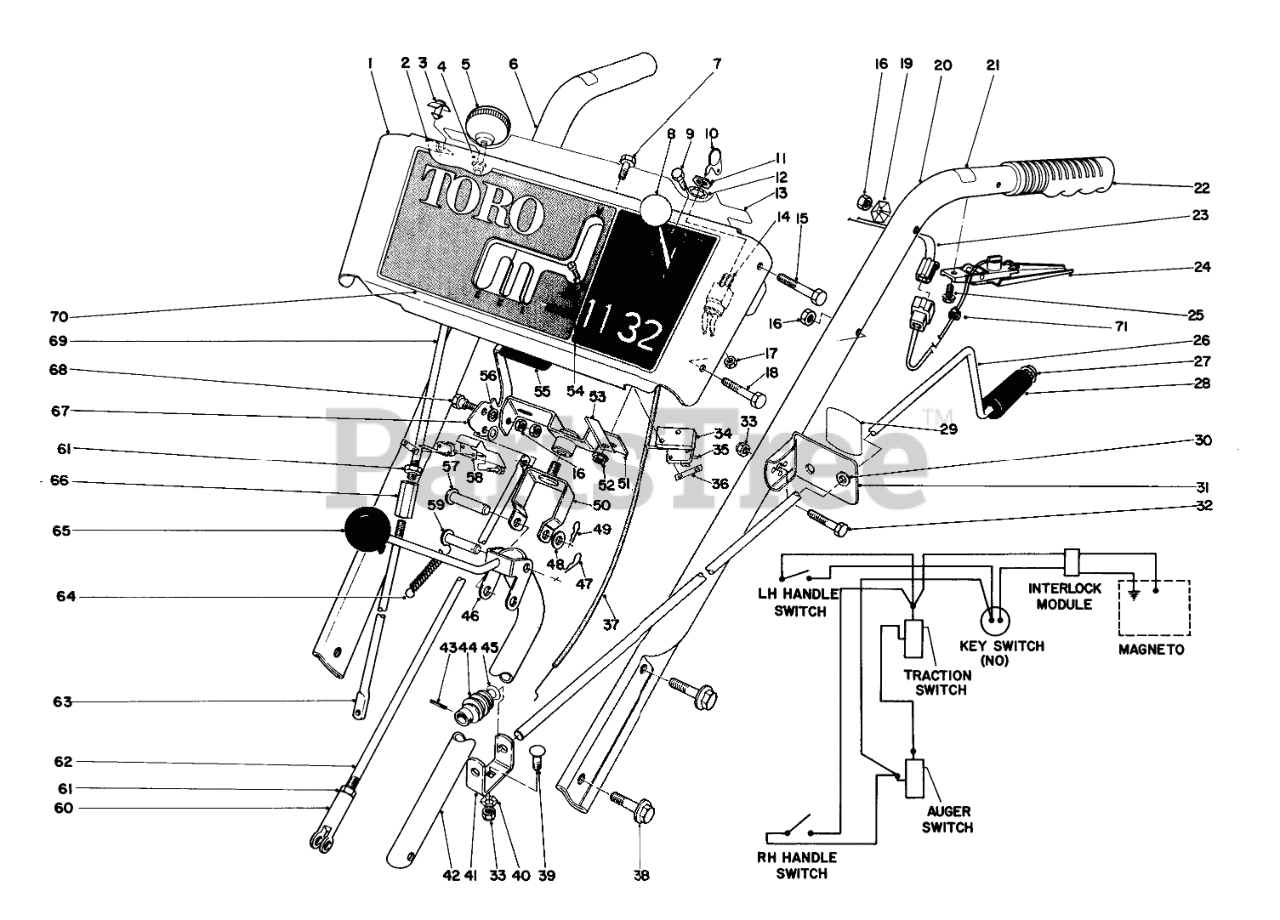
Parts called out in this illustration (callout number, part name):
1	Escutcheon Plate (Incl. Ref. #13 & 70)
2	WIRE CLAMP
3	Mounting Stud
4	NYLINER #6LI-FF TYPE 7
5	KNOB-LEVER
6	Handle Right
7	SCREW-HH
8	CONTROL KNOB
9	HEX HEAD SEMS 10-24X1/2
10	Key
11	NUT-HH
12	WASHER-TOOTH, INTERNAL
13	BACK ESCUTCH DECAL
14	Key Switch (Incl. Ref. #11 & 12)
15	SCREW-HH
17	NUT-LOCK, NI
18	SCREW-HH
19	Hairpin Cotter
20	HANDLE LEFT
21	INTERLOCK DECAL
22	Grip Handle
23	Wire Harness (Incl. Ref. #71)
24	INTERLOCK HDLE SWITCH
25	SCREW
26	Chute Control Rod
27	RETAINER-PUSH ON
28	GRIP-CONTROL, CHUTE
29	CHUTE DECAL
30	Bushing
31	Bracket-Chute Control Mtg. (Incl. Ref. #29 & 30)
32	SCREW-HH
33	NUT-LOCK, NI
34	SWITCH MTG PAD
35	SWITCH-MICRO
36	Speed Nut
37	Throttle Contrl
38	SCREW-HHF
39	BOLT-CARR
40	WASHER-LOCK
41	WORM BRACKET
42	Rod Traction Shift
43	PIN-SPRING
44	GEAR-WORM, CHUTE
45	WASHER-SPRING
46	SHIFT ROD WA
47	PIN-COTTER
48	WASHER-FLAT
49	PIN-HAIR
50	PIVOT BRKT WA
51	SWIVEL BLOCK WA
52	NUT-LOCK, HHF
53	Retainer Wire
54	SCREW-SPH
55	AUGER CLUTCH HND GRIP
56	WASHER-PLAIN
57	PIN-CLEVIS
58	SWITCH BRKT
59	PIN-CLEVIS
60	CLEVIS
61	NUT-HJ
62	DRAG LINK
63	LOWER WHL CLUTCH ROD
64	CONT ROD SPRING 0
66	WHL ROD COUPLING
67	Auger Clutch Handle
68	SCREW-SHOULDER
69	UP WHEEL CLUTCH ROD
70	ESCUTCHEON DECAL
71	Mount-Wire
